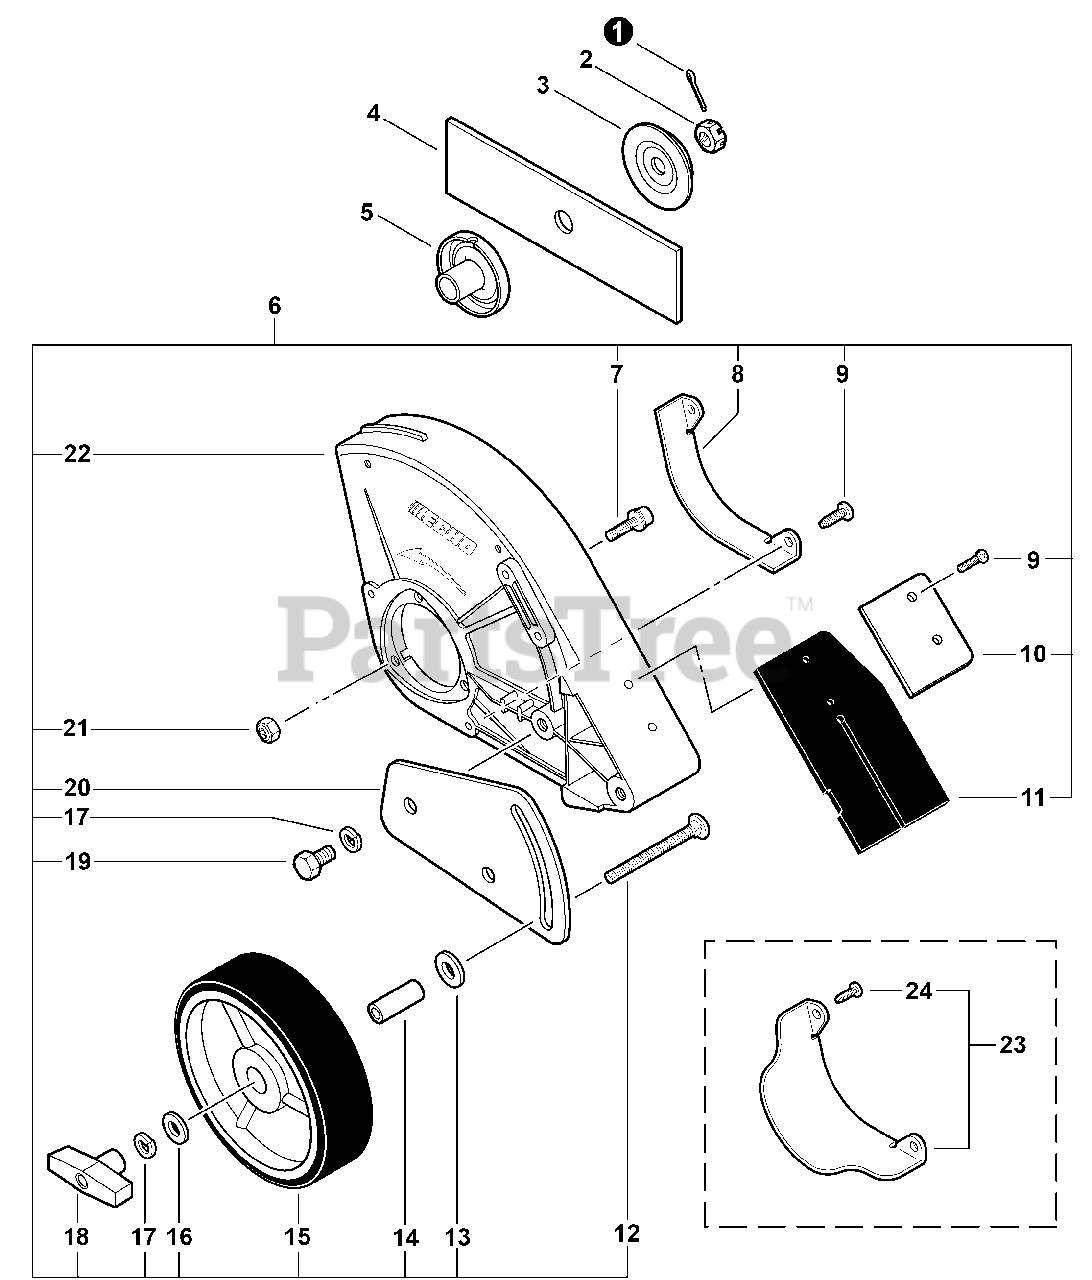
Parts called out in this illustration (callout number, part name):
1	PIN, COTTER 2×22
2	NUT 10×1.25 LH
3	PLATE, ADAPTOR - LOWER
4	BLADE - 2 PK
5	PLATE, ADAPTOR - UPPER
6	SHIELD KIT
7	BOLT 5×25
8	GUARD, SHIELD
9	SCREW 4×12
10	PLATE, FLAP
11	FLAP, DEBRIS
12	BOLT 5/16"-18×2-1/2"
13	WASHER, SPRING 10
14	COLLAR 12
15	WHEEL
17	WASHER, SPRING 8
18	KNOB, FASTENER
19	BOLT 8×14
20	BRACKET, WHEEL
21	NUT, LOCK M5
22	SHIELD, BLADE
23	GUARD KIT, SHIELD
24	SCREW 4×12
